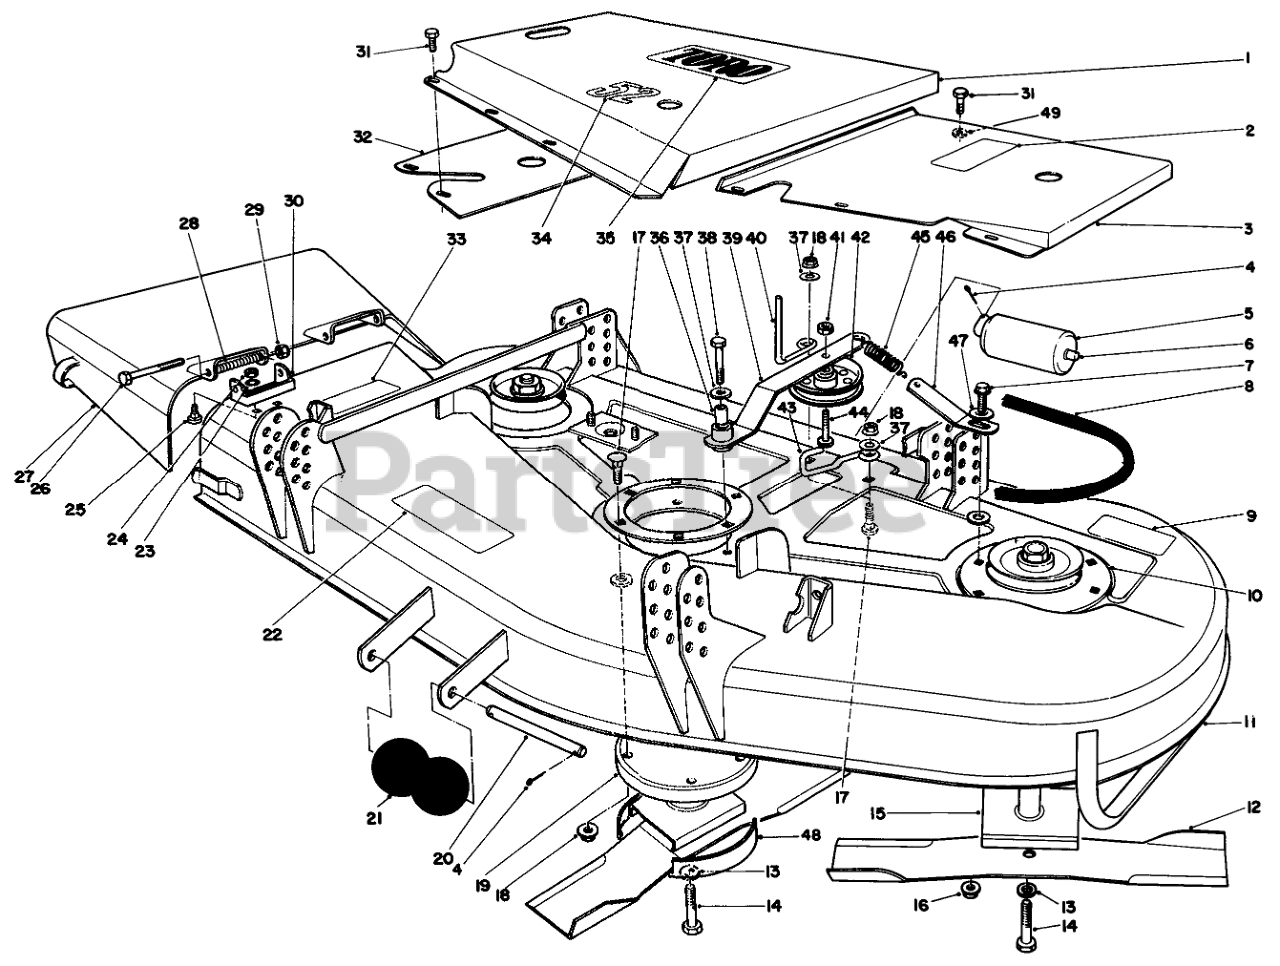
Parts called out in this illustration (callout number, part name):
1	CENTER COVER WA 52 R
2	DECAL
3	Cover
4	PIN-COTTER
5	ROLLER-DECK
6	SHAFT-ROLLER, REAR
7	SCREW-HHF
8	V-BELT
9	DECAL-CAUTION, BLADE
10	SUPPORT-DECK, RING
11	Deck Assembly
12	Blade
13	WASHER-LOCK
14	SCREW-BLADE
15	SPINDLE ASM
16	NUT-LOCK, FLANGE
17	SCREW-CARR
18	NUT-HF
19	HOUSING - SPINDLE ASM
20	SHAFT-ROLLER
21	ROLLER
22	Decal-Caution
23	WASHER-LOCK
24	NUT-HEX
25	SCREW-CARR
26	SCREW-HH
27	Deflector
28	SPRING
29	NUT-HEX
30	Bracket-Pivot
31	SCREW-HHFTF
32	Cover
33	DECAL-CAUTION, DEFLECTOR
34	DECAL
35	Decal-Toro
36	SLEEVE
37	WASHER-FLAT
38	SCREW-HH
39	Arm-Idler
40	ROD-BELT
41	NUT-HEX
42	Pulley
43	GUIDE-BELT
44	Bolt-Special
45	SPRING-EXTENSION
46	PLATE-SPRING
47	WASHER-FLAT
48	Cup-Scalp
49	WASHER-FLAT
